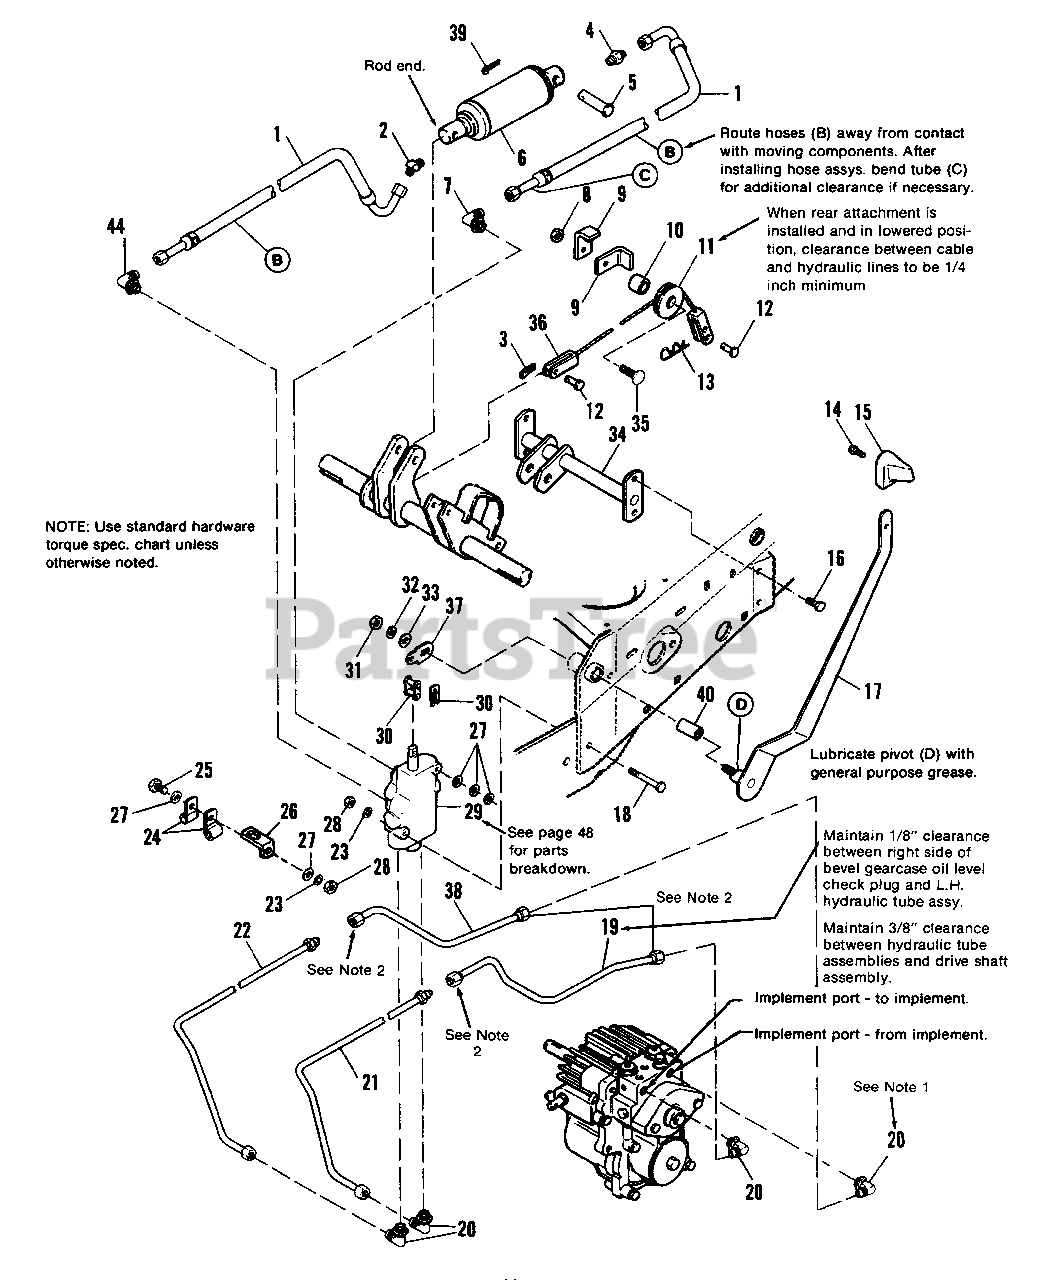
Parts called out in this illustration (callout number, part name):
1	HOSE, Hydraulic
2	ELBOW, 45ø Male
3	PIN, Cotter, 3/32 x 1
4	CONNECTOR, 37ø Male
6	CLYINDER, Hydraulic
7	ELBOW, Adjustable, 37ø
8	LOCKNUT, Hex, Jam, 3/8-16
9	GUARD, Cable
13	CLIP, Spring
14	SCREW, Hex, Wash. Hd., Taptite,1/4-20 x 1-1/4
16	SCREW, Hex, Wash. Hd., Taptite, 3/8-16 x 3/4
17	LEVER ASSY.
18	CAPSCREW, Hex Hd., 1/4-20 x 2-1/4
20	ELBOW, Adjustable, 37ø
23	LOCKWASHER, 1/4
25	CAPSCREW, Hex Hd., 1/4-20 x 1-1/4
27	WASHER, Plain, 1/4
28	NUT, Hex, Full, 1/4-20
29	CONTROL VALVE ASSY. (See page 46)
30	LINK, Connecting
31	NUT, Hex, Full, 3/8-16
32	LOCKWASHER, 3/8
33	WASHER, Plain, 3/8
34	SUPPORT ASSY.
35	SCREW, Special
36	CABLE ASSY.
39	PIN, Cotter
